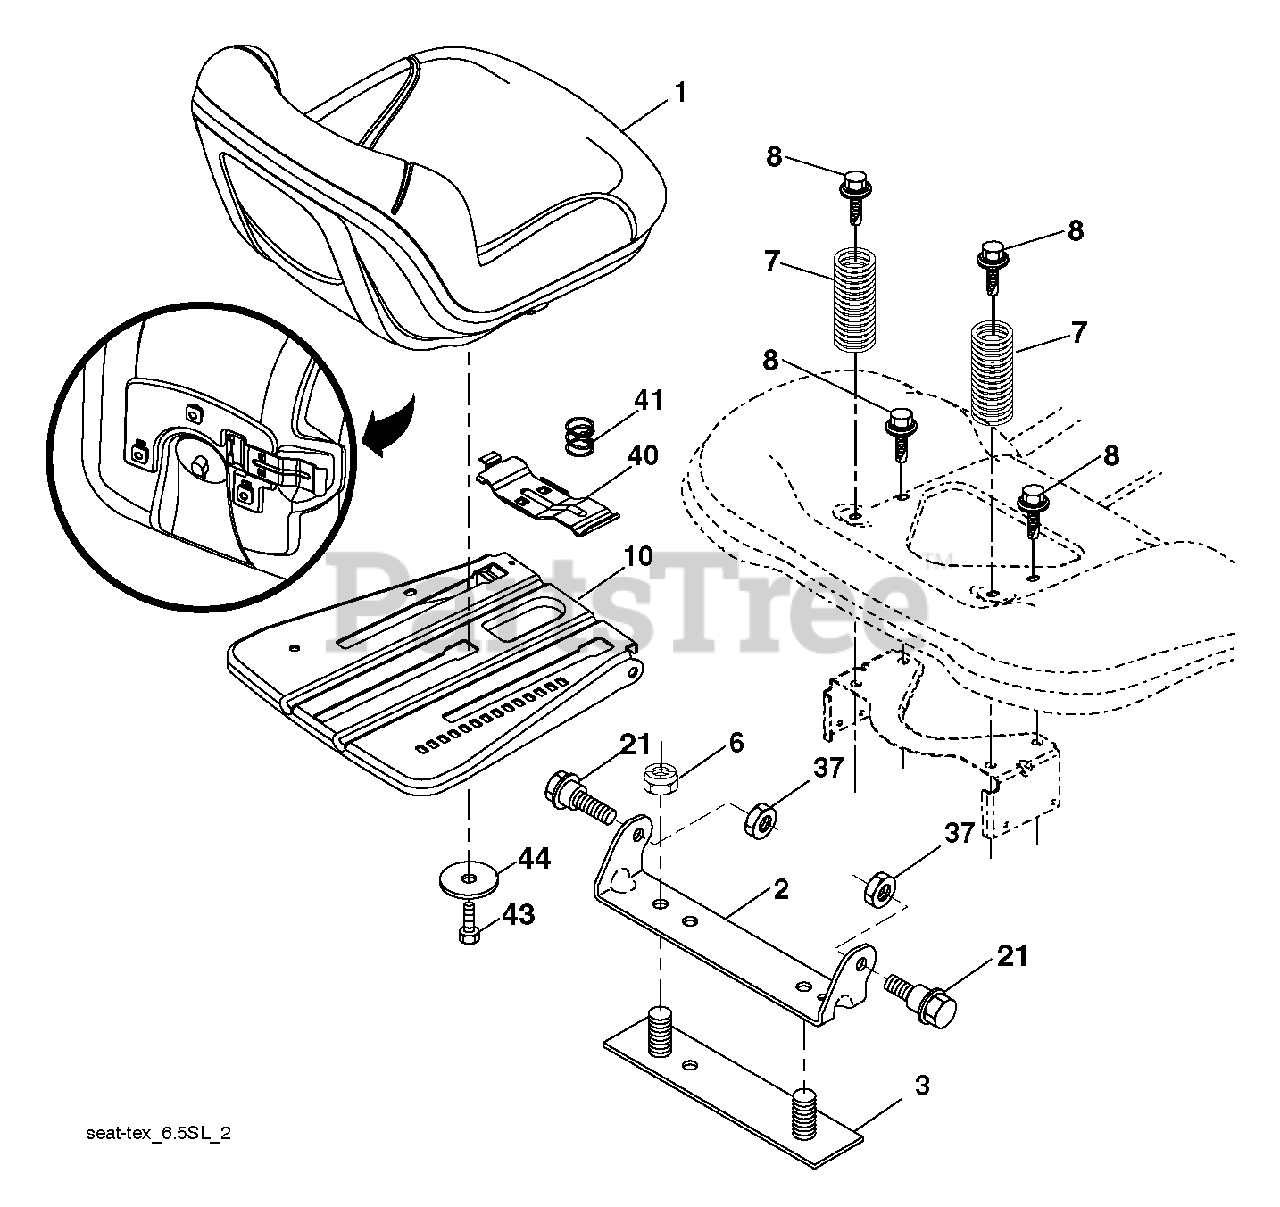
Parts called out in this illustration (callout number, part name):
1	SEAT.TH130.GREY.HUSQ.TEX
2	BRKT.PIVOT.FENDER
3	STRAP
6	NUT
7	SPRING COMPRESSION
8	BOLT, 5/16-18 X 1 3/4
10	PAN.ASM.SEAT.3PT
21	BOLT.SHOULDER.5/16-18
37	NUT.71038.31-18.HEX.NYLOCK
40	HANDLE.SLIDE.SEAT.TEX.BLACK
41	SPRING.LATCH.SEAT.TEX
44	WASHER 13/32 X 2-3/8 X 12GA
